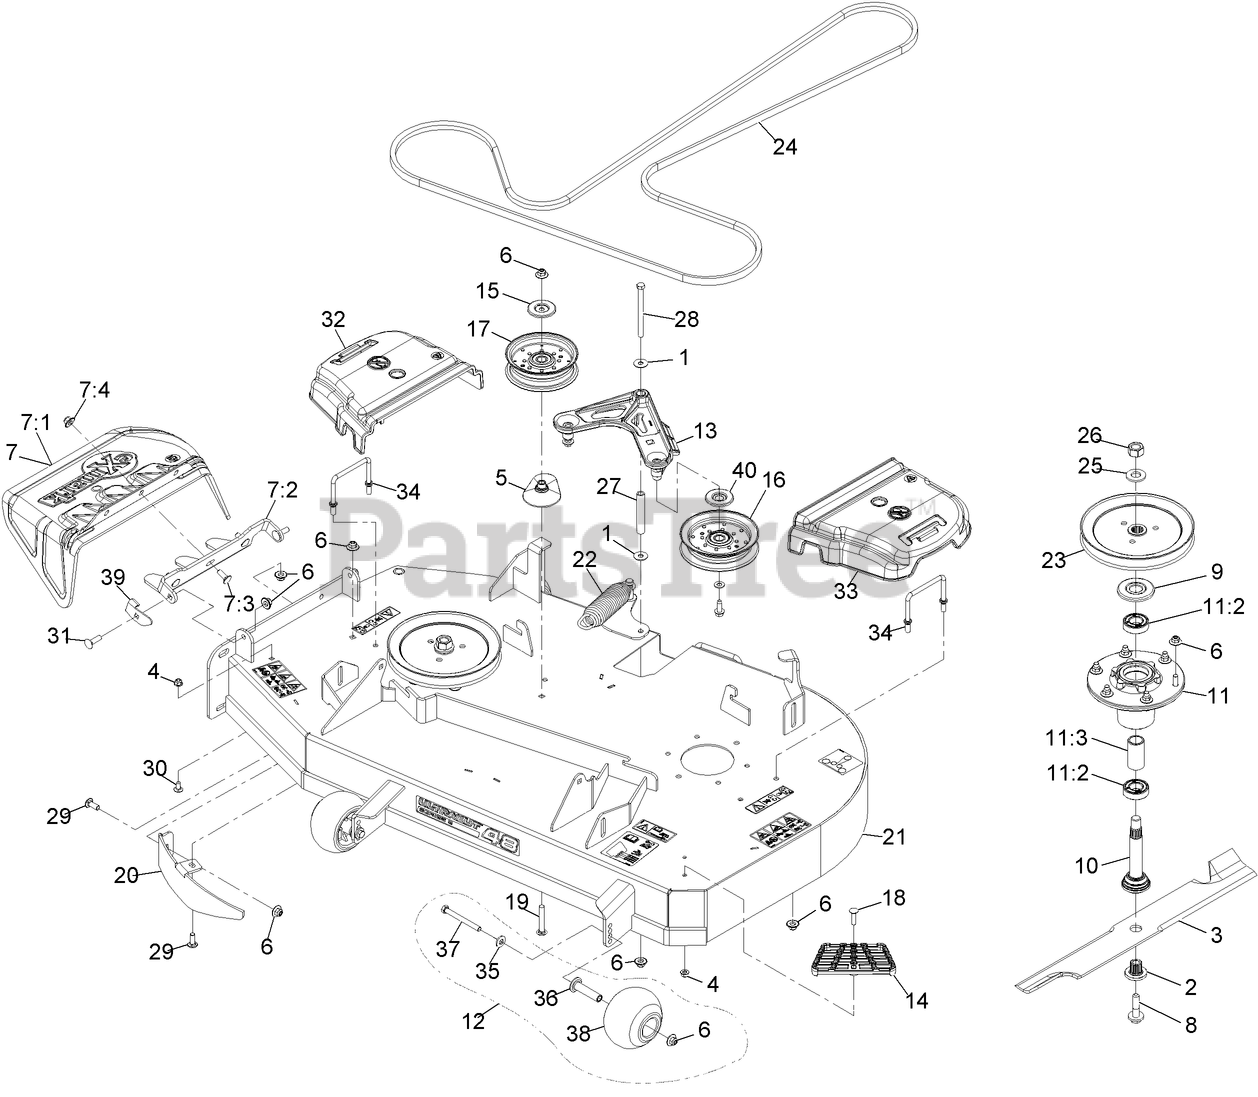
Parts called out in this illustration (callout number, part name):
2	BUSHING,SPLINED
4	NUT-HF, NI
5	SPACER-PULLEY
6	Nut-Nyloc 3/8-16 Flg
7	ASM,DISCHARGE CHUTE
7:1	CHUTE,DISCHARGE
7:2	BRACKET,DISCHARGE CHUTE
7:3	SCREW-CARR
7:4	Nut-Nyloc 3/8-16 Flg
8	SCREW,SEMS 1/2-20 X 2.19
9	GUARD,BEARING TOP .989
10	ASM-SPINDLE AND SEAL
11	ASM-CUTTER HSG WITH BEARINGS
11:2	BEARING-BALL
11:3	SPACER-BEARING
12	KIT, ANTI-SCALP ROLLER
13	IDLER ARM ASM
14	STEP-DECK
15	SHIELD-DUST
16	IDLER-PULLEY, FLAT
17	IDLER-PULLEY, FLAT 5.00X1
18	Bolt-Carriage 5/16-18 X 1 1/4
19	SCREW-CARR
20	Baffle-Discharge 48 2Blade
21	DECK-48 W\DECALS
22	SPRING-EXTENSION
23	SHEAVE-BLADE DRIVE, 8.40
24	BELT, B147.25
26	NUT-HEX
27	BUSHING
28	SCREW-HH
29	SCREW-CARR
30	SCREW-CARR
31	BOLT-CARR
32	COVER-BELT RH
33	COVER-BELT LH
34	WIREFORM-COVER
35	WASHER-BELLEVILLE
36	AXLE, ROLLER
37	SCREW-HH 3/8-16 X 3 3/4 GR 8
38	ROLLER-SCALP, ANTI
39	STOP-DISCHARGE CHUTE
40	SHIELD-GUARD, DUST
